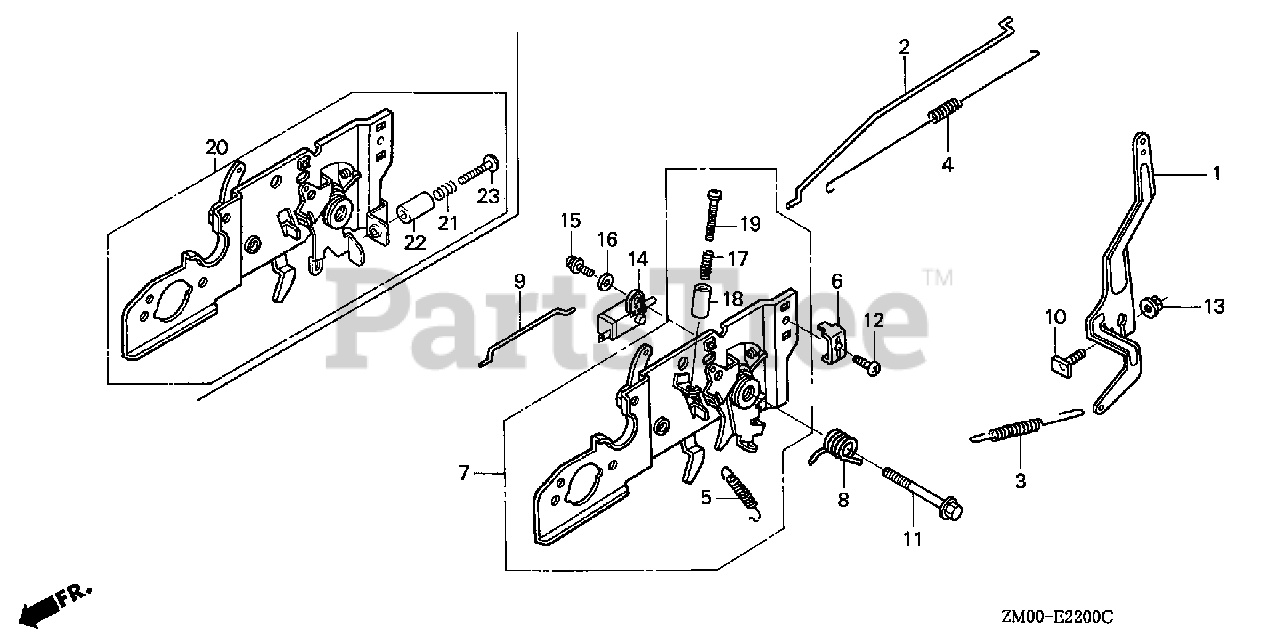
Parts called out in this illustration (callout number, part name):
1	ARM, GOVERNOR
2	ROD, GOVERNOR
3	SPRING, GOVERNOR
4	SPRING, THROTTLE RETURN
5	SPRING, LEVER
6	HOLDER, CABLE
7	BASE, CONTROL
8	SPRING, CONTROL LEVER RETURN
9	ROD, CHOKE
10	BOLT, GOVERNOR ARM
11	BOLT, FLANGE (6X45) (CT200)
12	SCREW, PAN (5X16)
13	NUT, FLANGE (6MM)
14	SWITCH ASSY., ENGINE STOP (N.O)
15	SCREW-WASHER (4X12)
16	WASHER, PLAIN (4MM)
